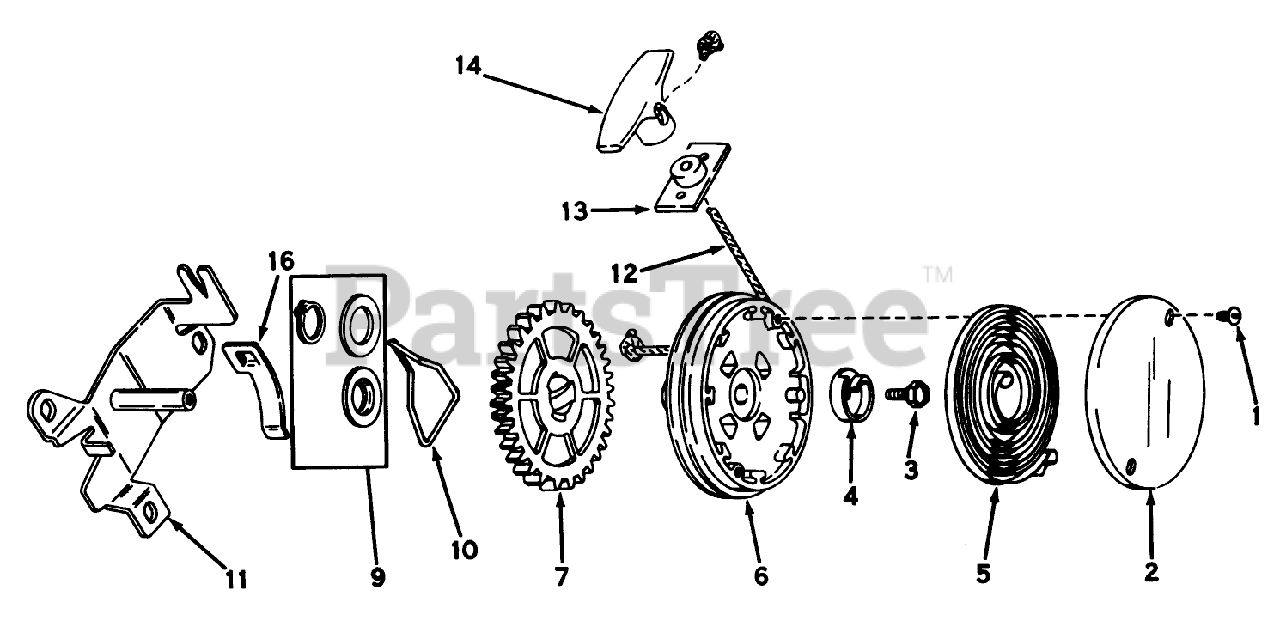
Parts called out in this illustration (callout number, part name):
1	Screw, Cover
2	Cover, Spring
3	Screw, Hex Washer Head
4	Hub Spring
5	Spring, Rewind
6	Pulley Assy. (Incl. No. 9)
9	Kit, Thrust Wash. Snap Rg.
10	Brake
11	Bracket Assy. Mounting
12	Rope, Starter
13	Bracket Assy.
14	Handle-Starter
16	Clip Rope
